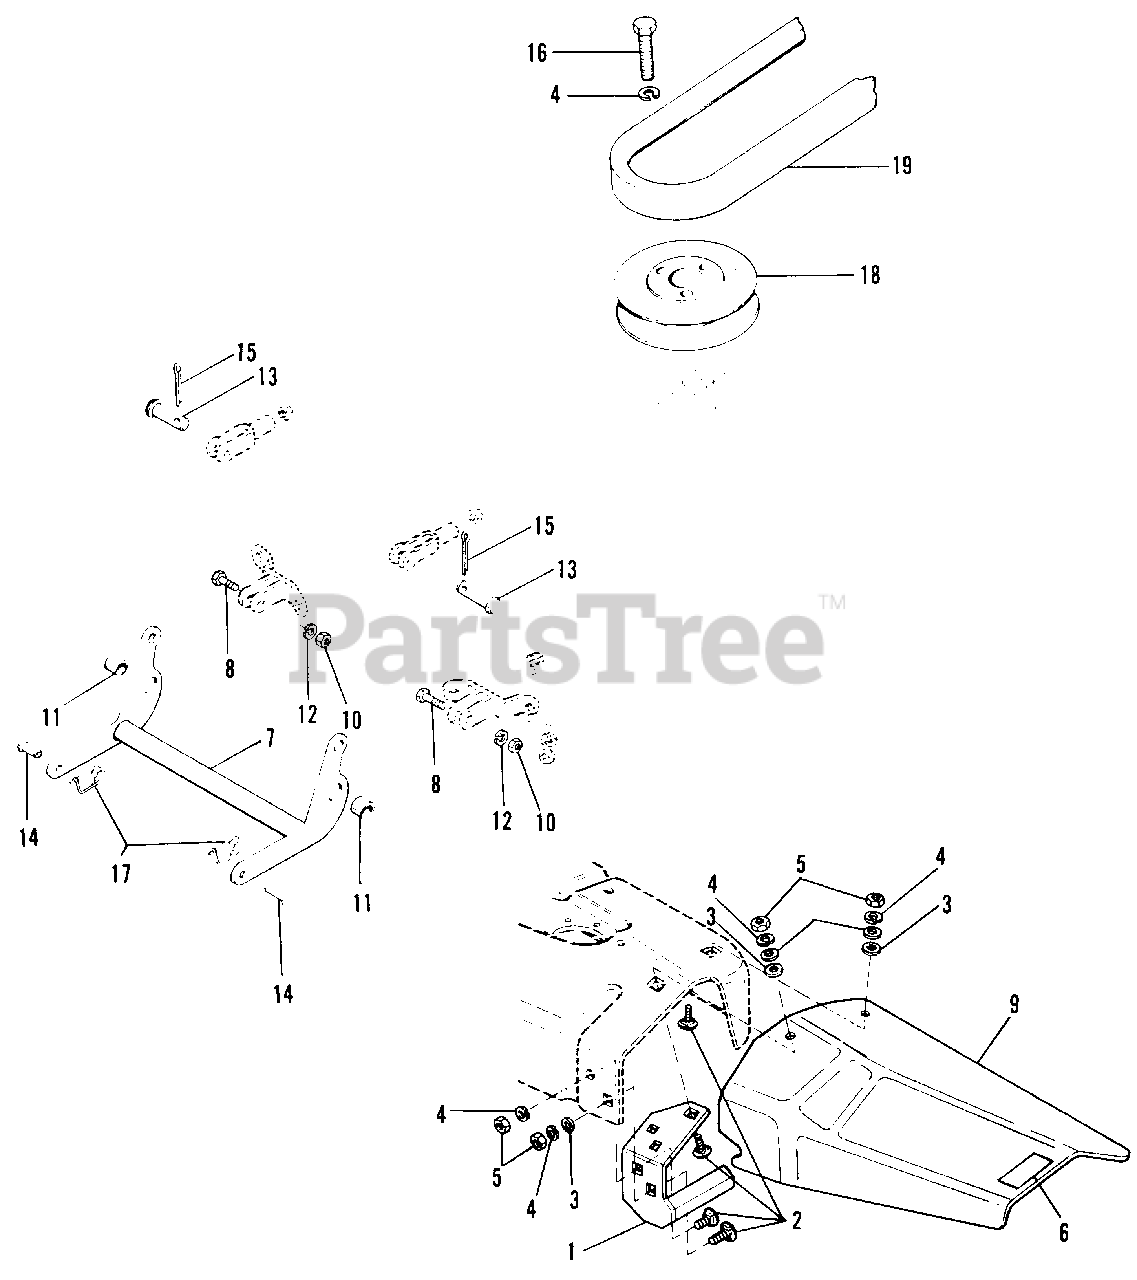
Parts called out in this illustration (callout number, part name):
1	GUARD ASSY, Stone
2	BOLT, Rd. Hd., 3/8-16 x 1-1/4
3	WASHER, Special
4	LOCKWASHER, Spring, 3/8
5	NUT, Hex, 3/8-16
6	DECAL, Danger
7	ARM ASSY, Rocker
8	CAPSCREW, Hex Hd., 1/2-13 x 1-1/4
10	NUT, Hex, 1/2-13
12	LOCKWASHER, Spring, 1/2
13	PIN, Yoke
14	PIN,
15	PIN, Cotter, 1/8 x 1
16	CAPSCREW, Hex Hd., 3/8-16 x 1-3/4, Gr. 8
17	CLIP, Safety Pin
19	BELT, "V" Tractor to Mower
